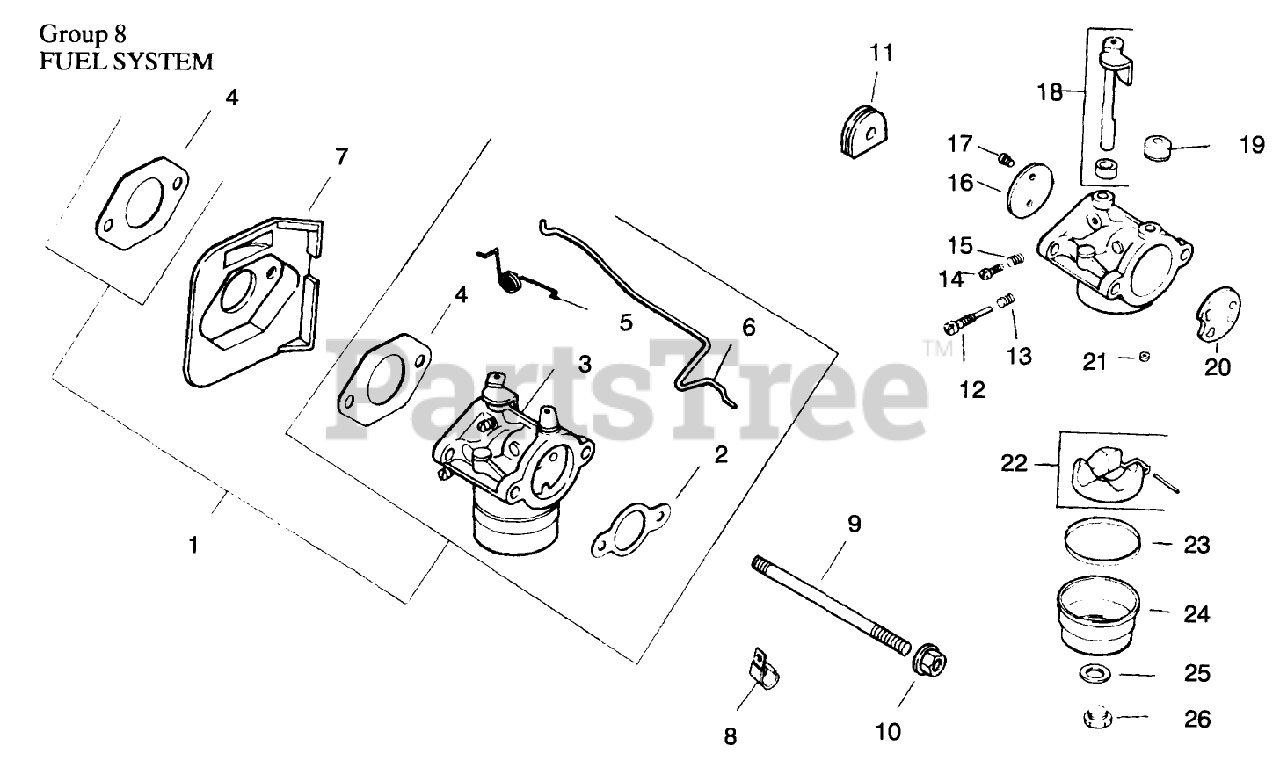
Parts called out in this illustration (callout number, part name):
1	Kit-Carburetor (Incl Ref. #2-6)
2	Gasket-Air Cleaner (Only On: 72042, 72043, 72062, 72063)
3	Carburetor Assembly (Incl Ref. #12-26)
4	Gasket-Carburetor (Only On: 72042, 72063, 72062, 72043)
5	Spring Choke
6	Linkage-Choke (Only On: 72042,72043,72062,72063)
7	Deflector-Heat (Only On: 72042,72043,72062,72063)
8	Clip-Cable (Only On: 72103)
9	Stud M6x1.0x110 (Only On: 72042,72043,72062,72063)
11	Grommet (Only On: 72042, 72063, 72062, 72043)
12	Needle-Idle
13	Spring-Idle Fuel (Only On: 72042, 72063, 72062, 72043)
14	Screw-Idle Speed Adjust (Only On: 72042,72043,72062,72063)
15	Spring-Idle Fuel (Only On: 72042, 72063, 72062, 72043)
16	Plate-Throttle (Only On: 72042,72043,72062,72063)
17	Screw-Throttle Plate (Only On: 72042,72043,72062,72063)
18	Shaft-W/Lever Seal (Only On: 72042, 72063, 72062, 72043)
19	Cap-Choke Lever
20	Plate-Choke
21	Jet-Main
22	Kit-Float (Only On: 72042,72043,72062,72063)
23	Gasket-Bowl (Only On: 72042,72043,72062,72063)
24	Bowl-Fuel (Only On: 72042, 72063, 72062, 72043)
25	Gasket-Bowl Screw (Only On: 72042, 72063, 72062, 72043)
26	Screw-Fuel Bowl (Only On: 72042, 72063,72062, 72043)
